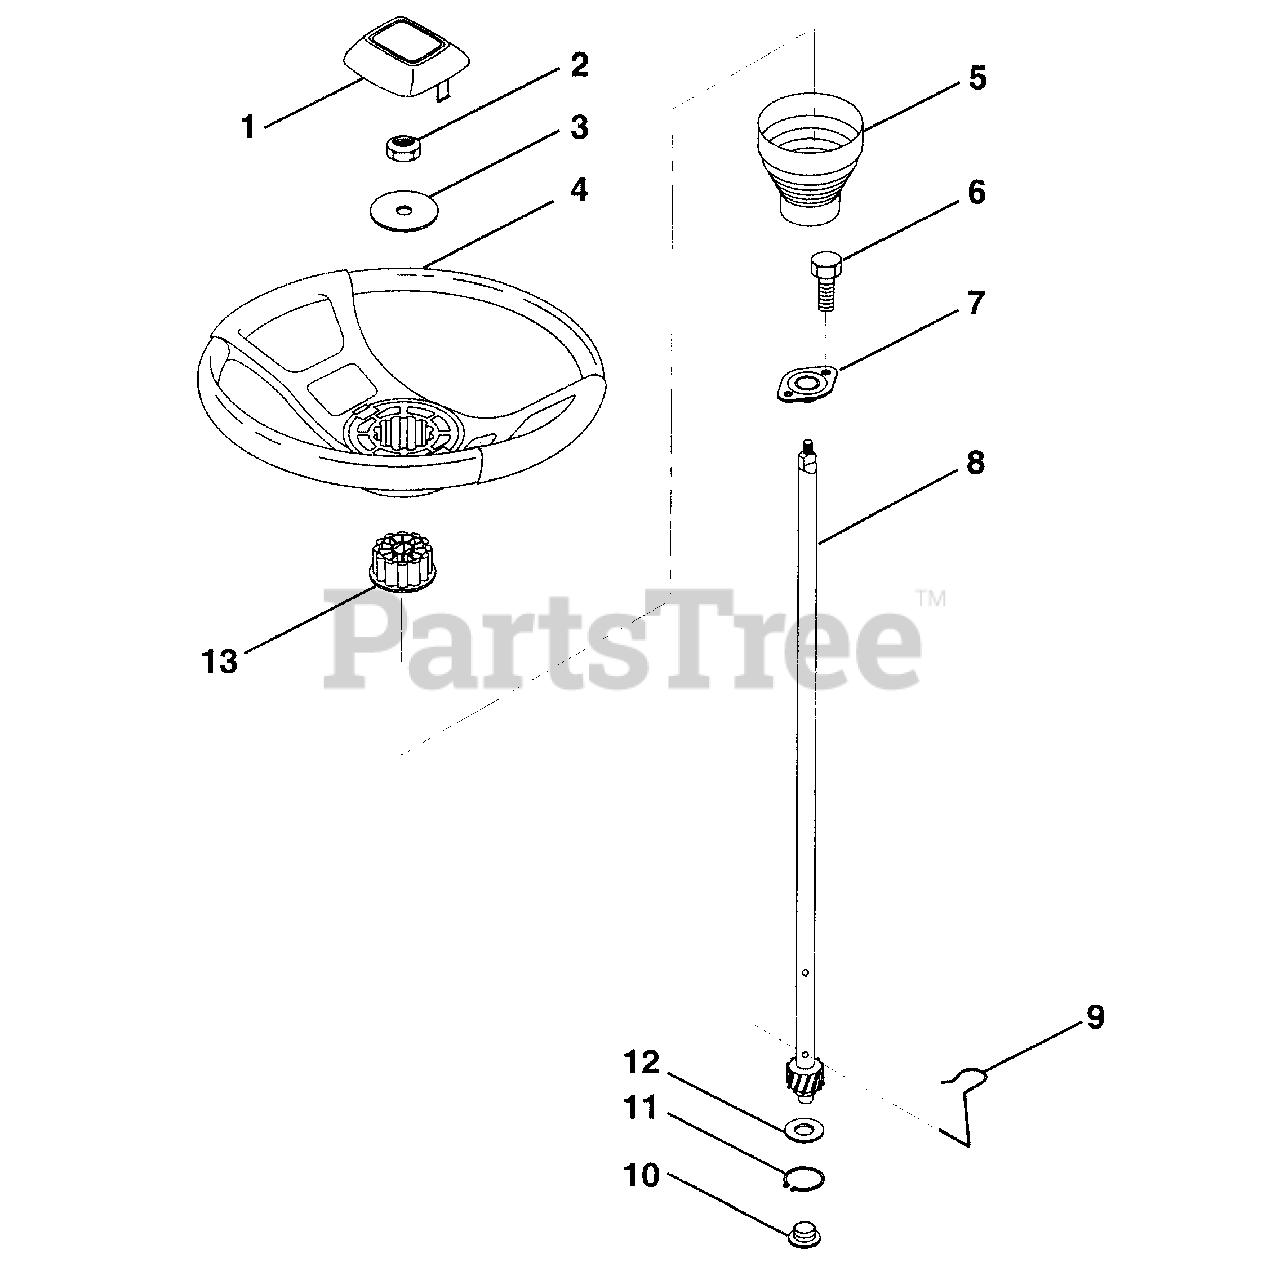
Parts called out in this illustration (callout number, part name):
1	Insert, Steering Wheel
2	Locknut 3/8-24 UNF
3	Washer 12/32 x 2-3/8 x 8 Gauge
4	Steering Wheel
5	Sleeve, Steering
6	Screw, Hex Head #10-16 x 1/2
7	Bushing, Steering
8	Shaft, Steering
9	Clip, Steering
10	Bushing, Lower, Steering
11	Ring, Retaining
12	Washer 21/32 x 1 x 16 Gauge
13	Adaptor, Steering Wheel
